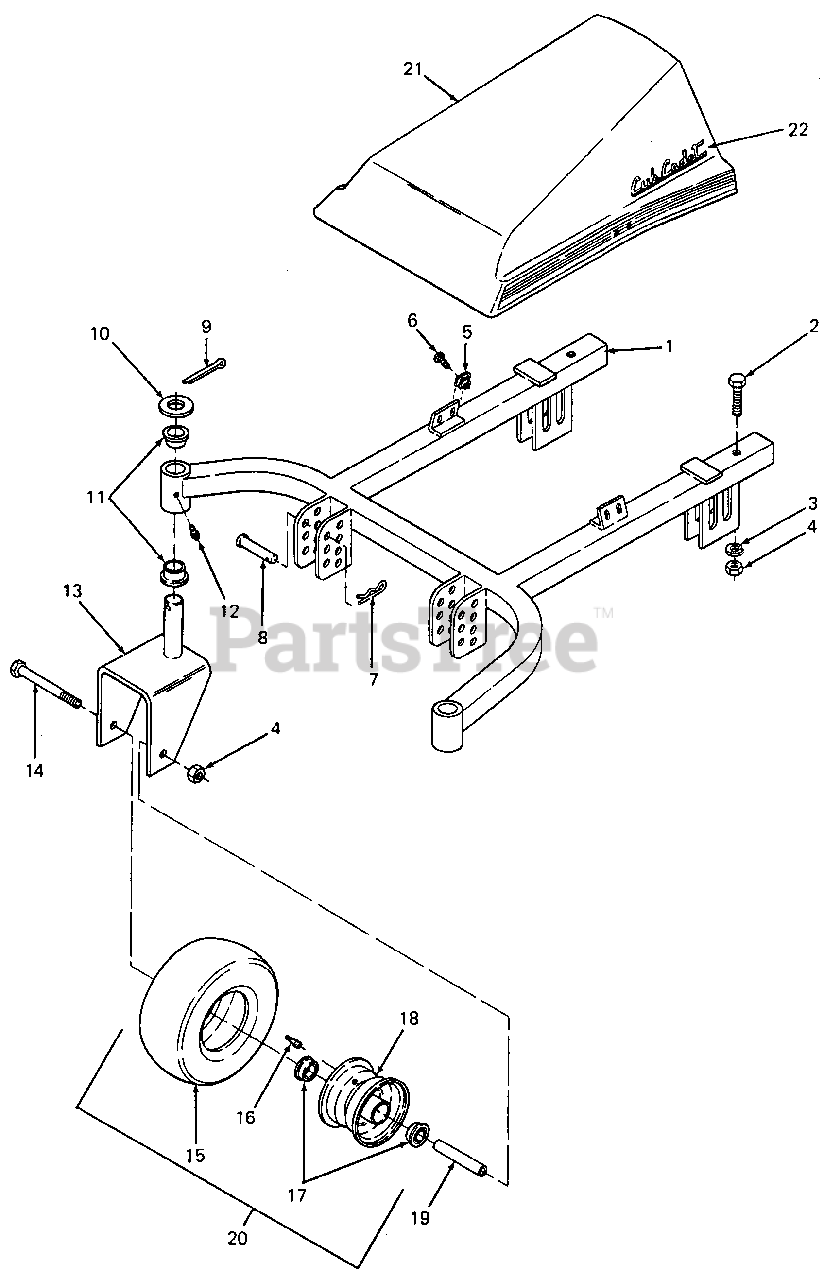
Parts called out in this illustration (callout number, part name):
1	Frame, Mower
2	Screw, Hex Cap, 1/2-13 X 2.0 Lg
3	Washer, Lock, 1/2
4	Nut, Hex Center Lock, 1/2-13
6	Screw, Truss Mach, 1/4-20 X .75 Lg
7	Cotter, Hairpin, 1/8
8	Pin, Clevis, 1/2 Dia X 2.5 Lg
9	Pin, Cotter, 1/4 Dia X 2.0 Lg
10	Washer, Flat, 1" Narrow
11	Bushing, Caster Fork
12	Fitting, Grease, 1/4-28 Str. Short
13	Fork, Caster
14	Screw, Hex Cap, 1/2-13 X 5.0 Lg
15	Tire, Smooth, 3.5-9 X 4
16	Stem, Valve
18	Wheel Assy w/Graphic
19	Spacer, Caster Wheel
20	Wheel Assy, Caster
21	Cover, Mower
22	Script, CCC
